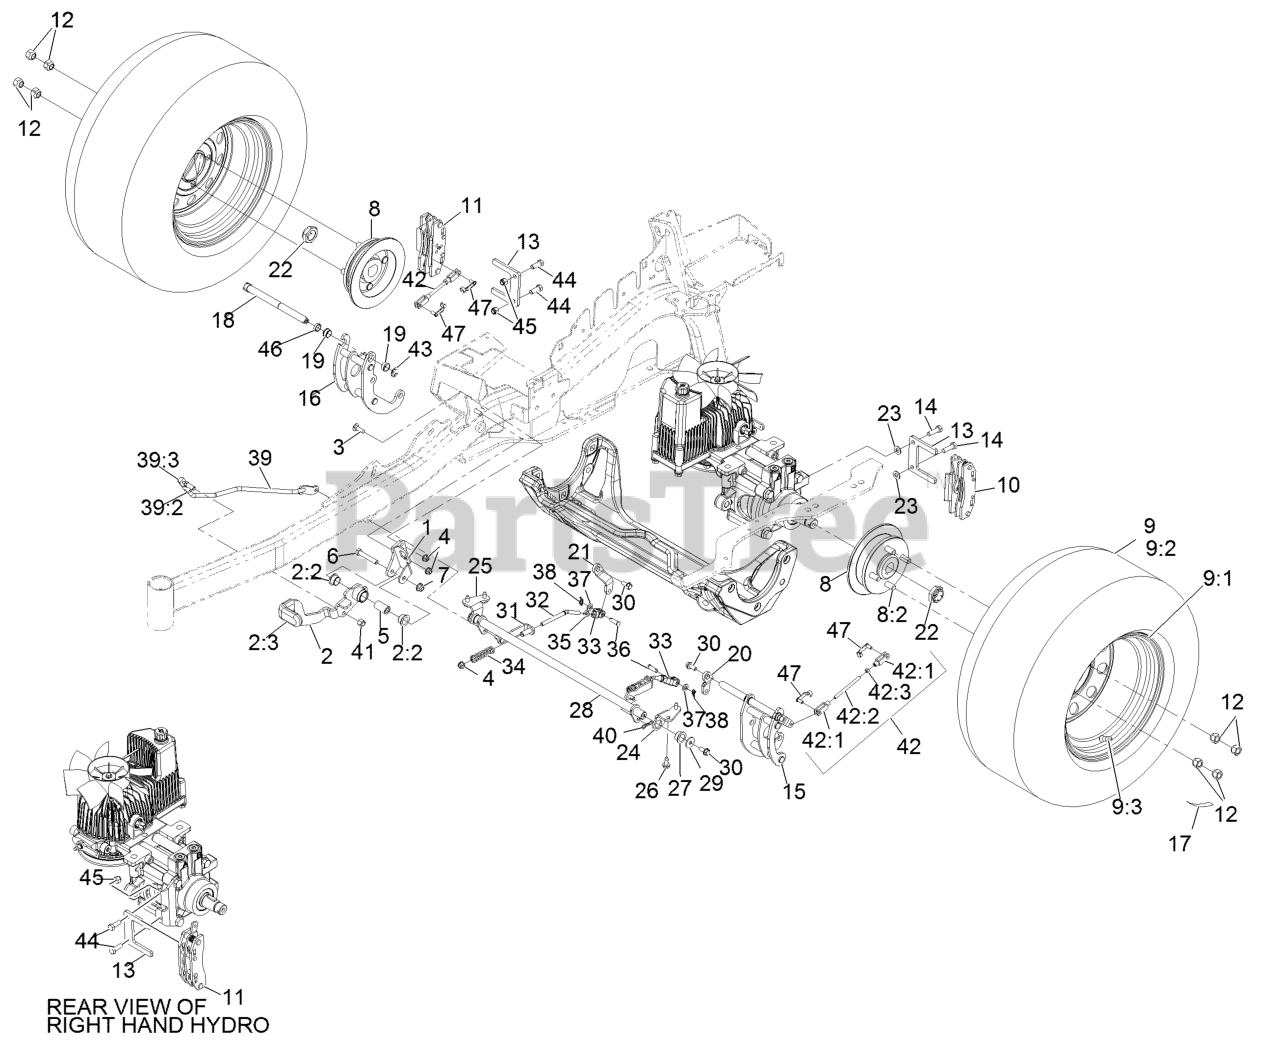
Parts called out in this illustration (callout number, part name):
1	BRACKET-MOUNT
2	BRAKE LEVER ASM W/ GRIP
2:2	BUSHING-FLANGE
2:3	GRIP-LEVER
3	BOLT-CARR
4	NUT-HF, NI
5	HANDLE-PIVOT, BRAKE
6	SCREW-HH
7	NUT-HF, NI
8	WHEEL HUB ASM
8:2	STUD-WHEEL
9	WHEEL AND TIRE ASM
9:1	ASM, RIM
9:2	TIRE-DRIVE, 23X9.5-12
9:3	Stem-Valve
10	CALIPER-BRAKE
11	CALIPER-BRAKE, RH
12	NUT-LUG
13	PLATE-MOUNT, BRAKE
14	SCREW-LOCK, PATCH
15	MOUNT-BELLCRANK, LH
16	MOUNT-BELLCRANK, RH
17	DECAL-TORQUE, WHEEL HUB LUG
18	BELLCRANK
19	BUSHING
20	ARM-INNER, LH
21	ARM-INNER, RH
22	LOCKNUT
23	WASHER-FLAT
24	MOUNT-PIVOT, LH
25	MOUNT-PIVOT, RH
26	Screw-HWH 5/16-18 X 3/4 Tf
27	BUSHING-FLANGE
28	SHAFT-CROSS
29	WASHER-FLAT
30	SCREW-HHF
31	BRACKET-L
32	LINKAGE-MID
33	YOKE-OFFSET
34	SPRING-COMPRESSION
35	NUT-JAM
36	PIN-CLEVIS
37	WASHER-PLAIN
38	PIN-COTTER, LOCKING
39	FRONT LINKAGE ASM
39:2	END-TIE ROD, RH
39:3	NUT-HJ
40	PIN-COTTER, LOCKING
41	NUT-LOCK
42	REAR LINKAGE ASM
42:3	NUT-JAM
44	SCREW-HH
45	NUT-LOCK, NI
47	PIN-CLEVIS, SPRING
